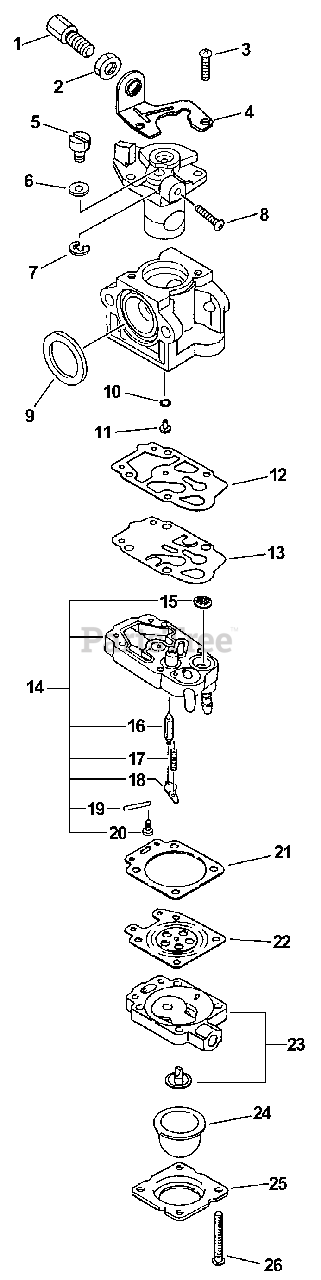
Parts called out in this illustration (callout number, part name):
1	ADJUSTER, THROTTLE CABLE
2	NUT, ADJUSTER LOCK M7
4	BRACKET, THROTTLE CABLE
9	SEAL
10	NEEDLE - MIXTURE
11	JET, MAIN
14	BODY ASSY, PUMP
15	STRAINER
16	VALVE, INLET NEEDLE
17	SPRING, METERING LEVER
18	LEVER, METERING
19	PIN, METERING LEVER
21	GASKET, METERING
22	DIAPHRAGM, METERING
23	BODY ASSY, PURGE
24	BULB, PURGE
25	RETAINER, PURGE BULB
